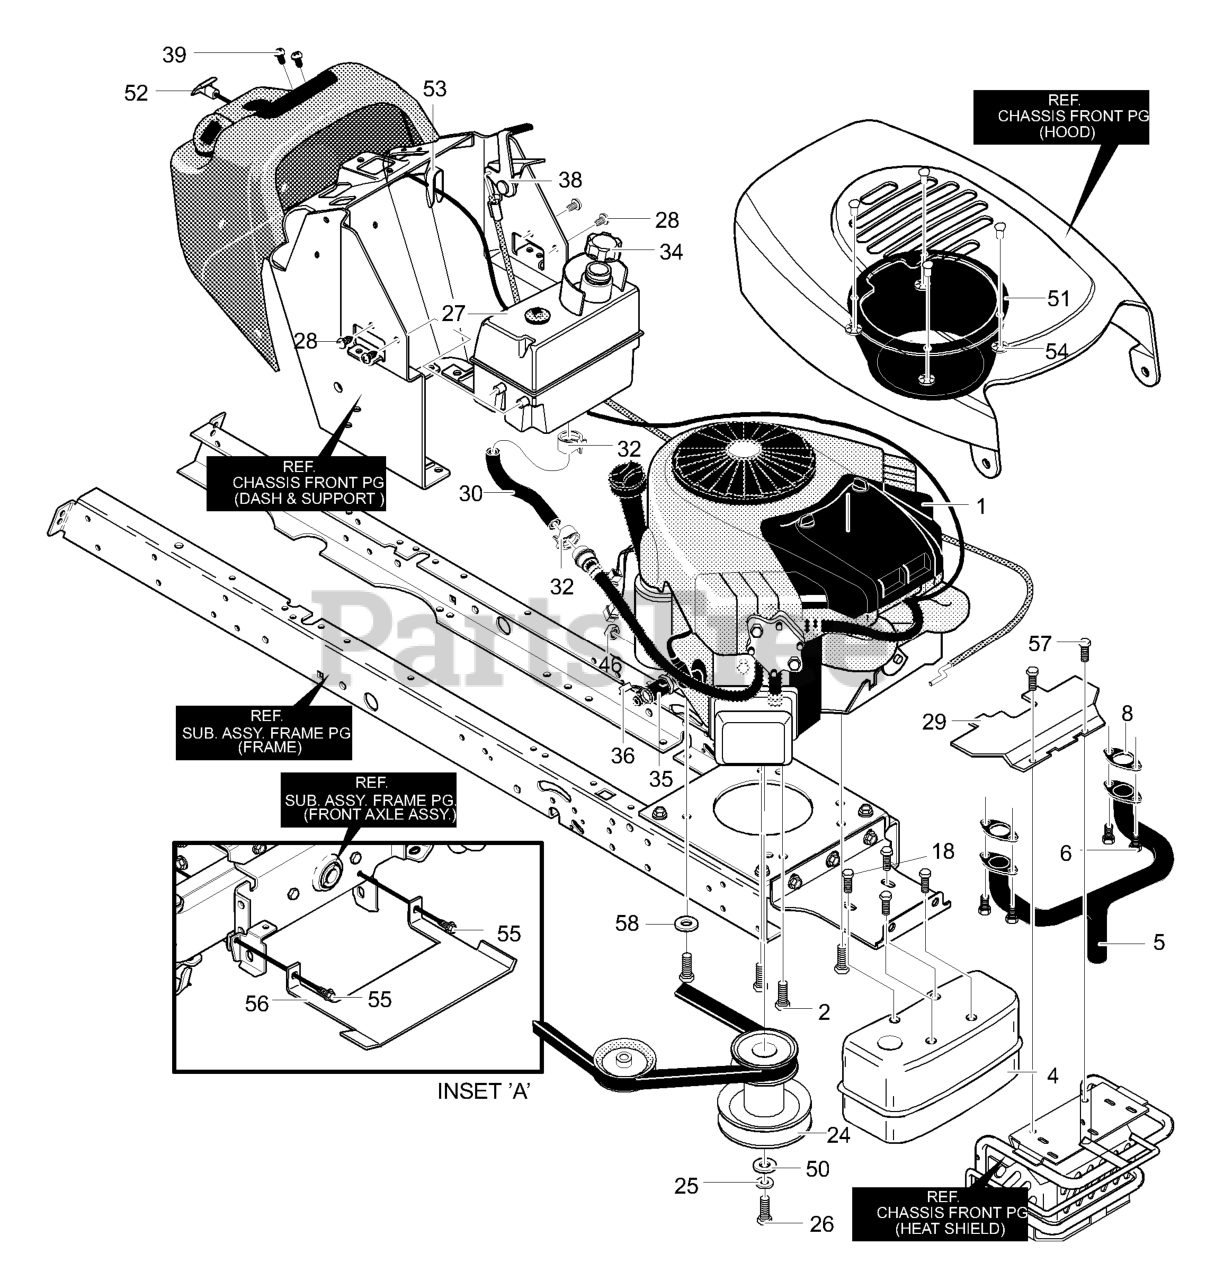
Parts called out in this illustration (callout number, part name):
2	Engine Bolt 3/8x1.25
4	Muffler
5	Exhaust Tube
8	Exhaust Gasket
18	SCREW, 1/4-20x.63
19	SPACER, Sleeve
24	Stack Pulley Assembly
25	WASHER, Regsptlk
26	BOLT, 7/16-20x1.75
27	Fuel Tank w/Sensor
28	SCREW, 15TPIX
29	Heat Shield
30	GAS LINE TUBING 14 In.
32	CLAMP, Fuel Line Yellow
34	Fuel Cap
35	Oil Drain Valve Assy.
36	Cap, Oil Drain Valve
38	Throttle Control
39	SCREW, #8-16x.50
46	NUT, 1/4-20 Reghexjam
50	Flat washer
51	Plenum, Hood
52	Choke Control
53	Clip, Choke Control
54	Pushnut
55	SCREW,5/16-18x.75
56	Anti-Dehydration Shield
57	SCREW, 1/4-20x.50
58	WASHER, Exlk
